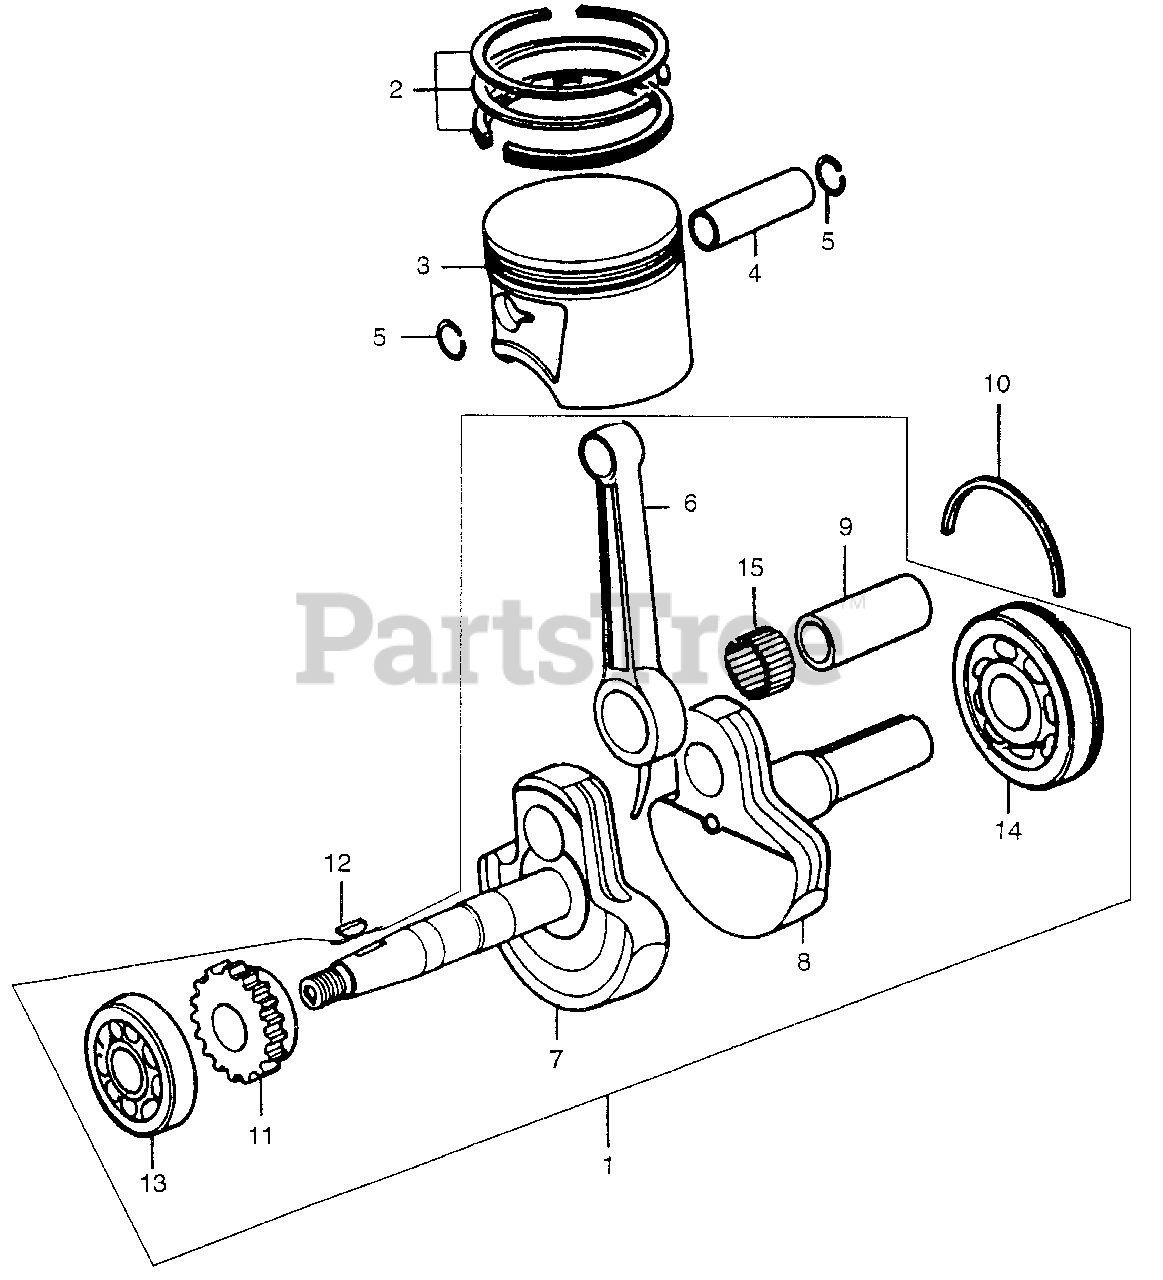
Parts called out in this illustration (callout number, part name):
2	RING SET, PISTON (STD)
2	RING SET, PISTON (OVER SIZE) (0.25)
2	RING SET, PISTON (OVER SIZE) (0.50) (NOT AVAILABLE)
2	RING SET, PISTON (OVER SIZE) (0.75) (NOT AVAILABLE)
3	PISTON (STD) (NOT AVAILABLE)
3	PISTON (OVER SIZE) (0.25)
3	PISTON (OVER SIZE) (0.50) (NOT AVAILABLE)
3	PISTON (OVER SIZE) (0.75) (NOT AVAILABLE)
4	PIN, PISTON (NOT AVAILABLE)
5	CLIP, PISTON PIN (18MM)
10	RING, BALL BEARING SET (NOT AVAILABLE)
11	GEAR, TIMING
12	KEY, WOODRUFF (NOT AVAILABLE)
13	BEARING, BALL (6304S) (NOT AVAILABLE)
14	BEARING, RADIAL BALL (6206SHS) (NOT AVAILABLE)
